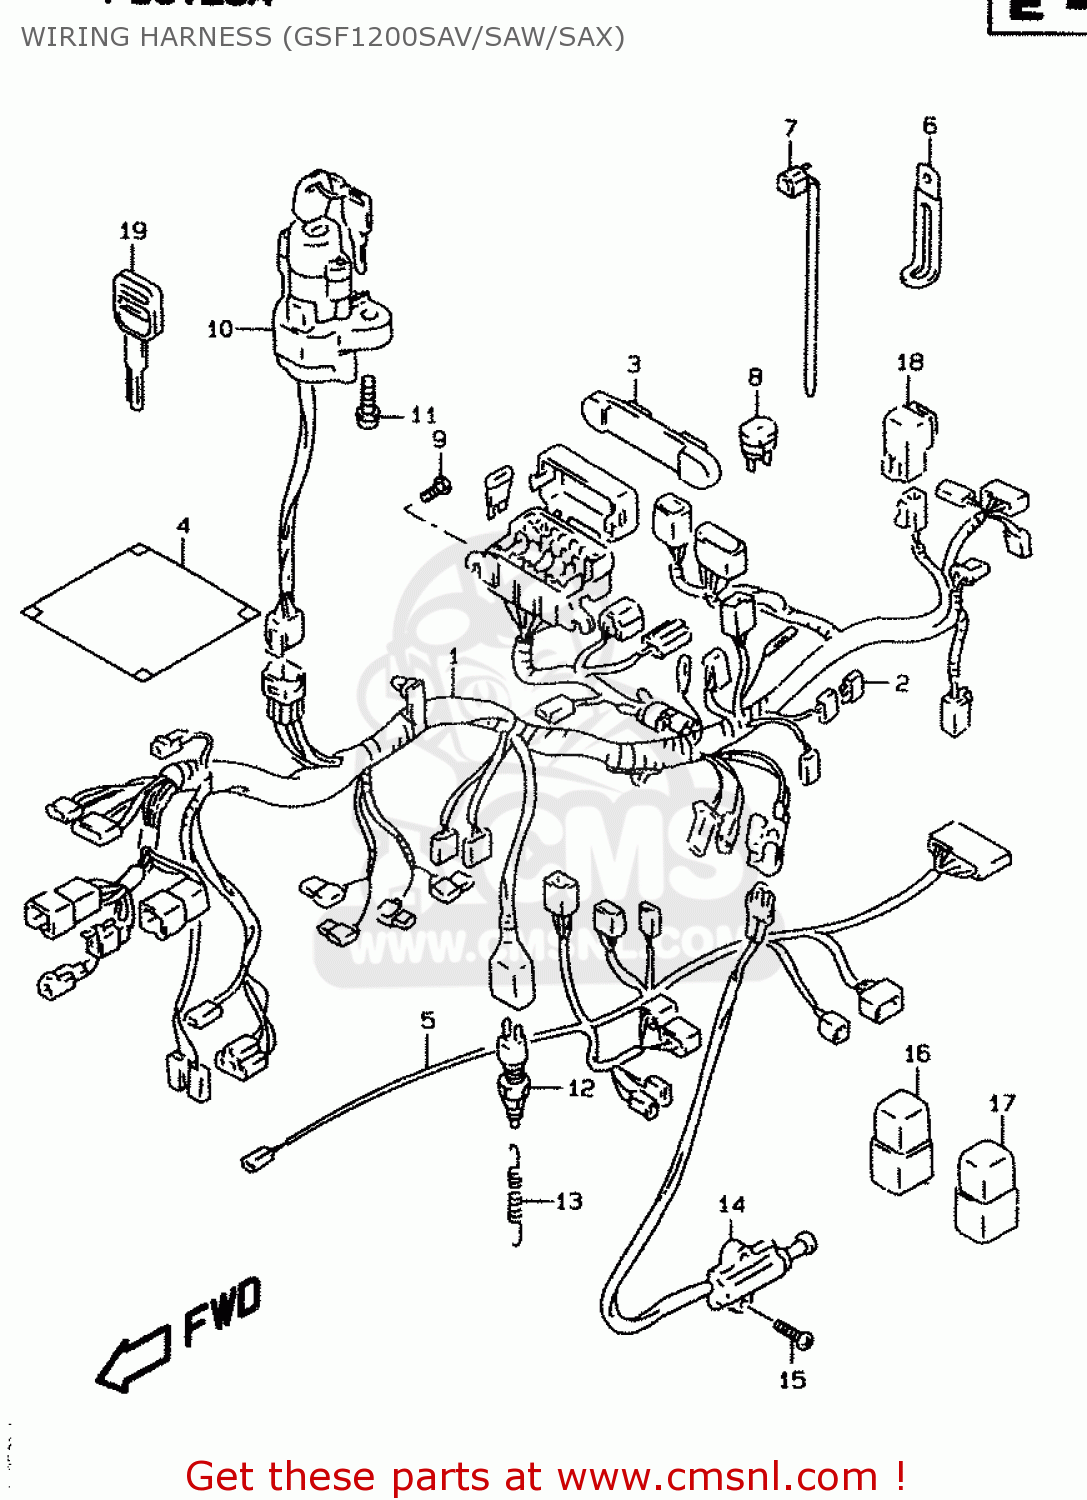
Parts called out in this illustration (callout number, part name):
1	HARNESS,WIRING NO.1
2	DIODE(STANLEY DE8804)
3	HOLDER,FUSE BOX
4	COVER,WIRING HARNESS
5	HARNESS,WIRING NO.2
6	CLAMP(L:65)
7	CLAMP(L:125)
8	BREAKER ASSY,CIRCUT
9	SCREW 6X12
10	LOCK ASSY,STEERING
11	BOLT(8X20)
12	SWITCH ASSY,STOP LAMP
13	SPRING
14	SWITCH ASSY,SIDE STAND
15	SCREW
16	RELAY ASSY,ABS MOTOR
17	RELAY ASSY,ABS VALVE
18	RELAY ASSY
19	KEY,BLANK
